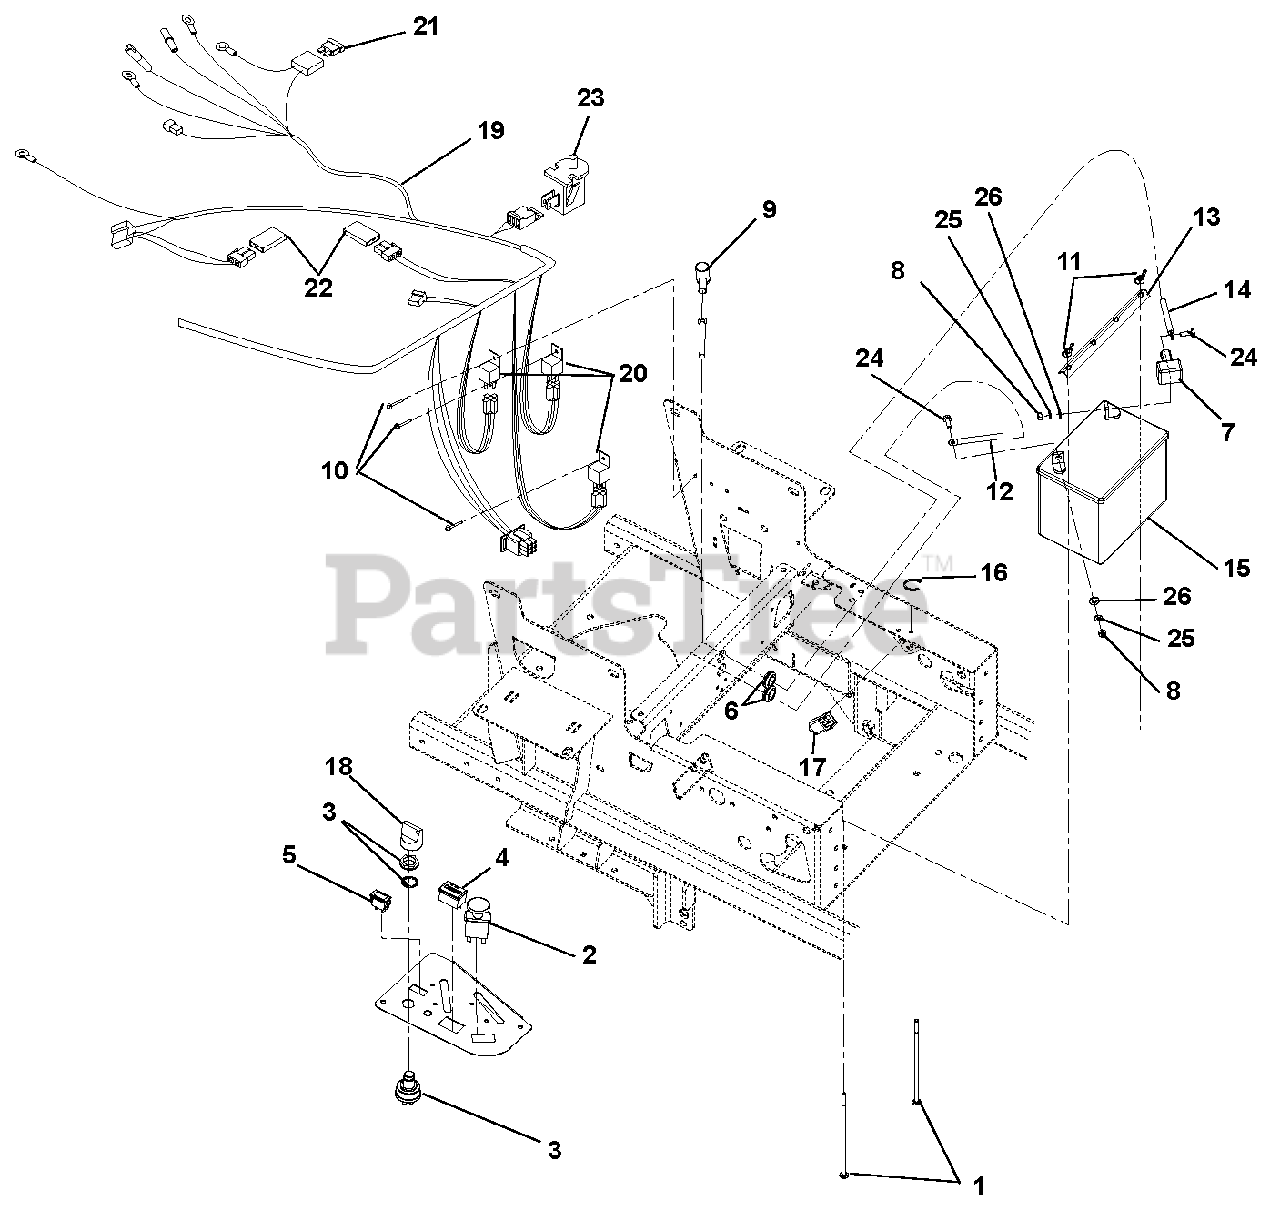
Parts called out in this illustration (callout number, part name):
1	Bolt, Round Head Square Neck .25-20 x 7.50
2	Switch, Clutch
3	Switch, Ignition
4	Hour Meter w/Maintenance
5	Light, Indicator (991079, 080, 081)
6	Bushing, Panel Snap .687 x .875 x .56
7	Insulator
8	Nut, Hex .25-20
9	Battery Terminal Boot, Red
10	Rivet, .25 Nylon Panel
11	Nut, Locking Wing .250-20
12	Ground Cable .31 x 22.00 x .31
13	Hold Down
14	Cable, Positive Battery 26.00"
15	Exide Battery, Sealed Maintenance Free U1-250
16	Cable Tie
17	Switch, Snap In-N.O./N.O.
18	Key, with Shield
19	Harness, Wire – Pro-Turn 100
20	Relay, Sealed with Diode
21	Fuse, 30 AMP.
22	Diode, Connector Shell
23	Switch, Snap Mounting (N.O.)
24	Bolt, Hex .25-20 x .75
25	Washer, Locking .25 x .062 Regular
26	Washer, Flat Steel .281 x .62 x .065
27	Harness, Kohler EFI (991095, 096)
